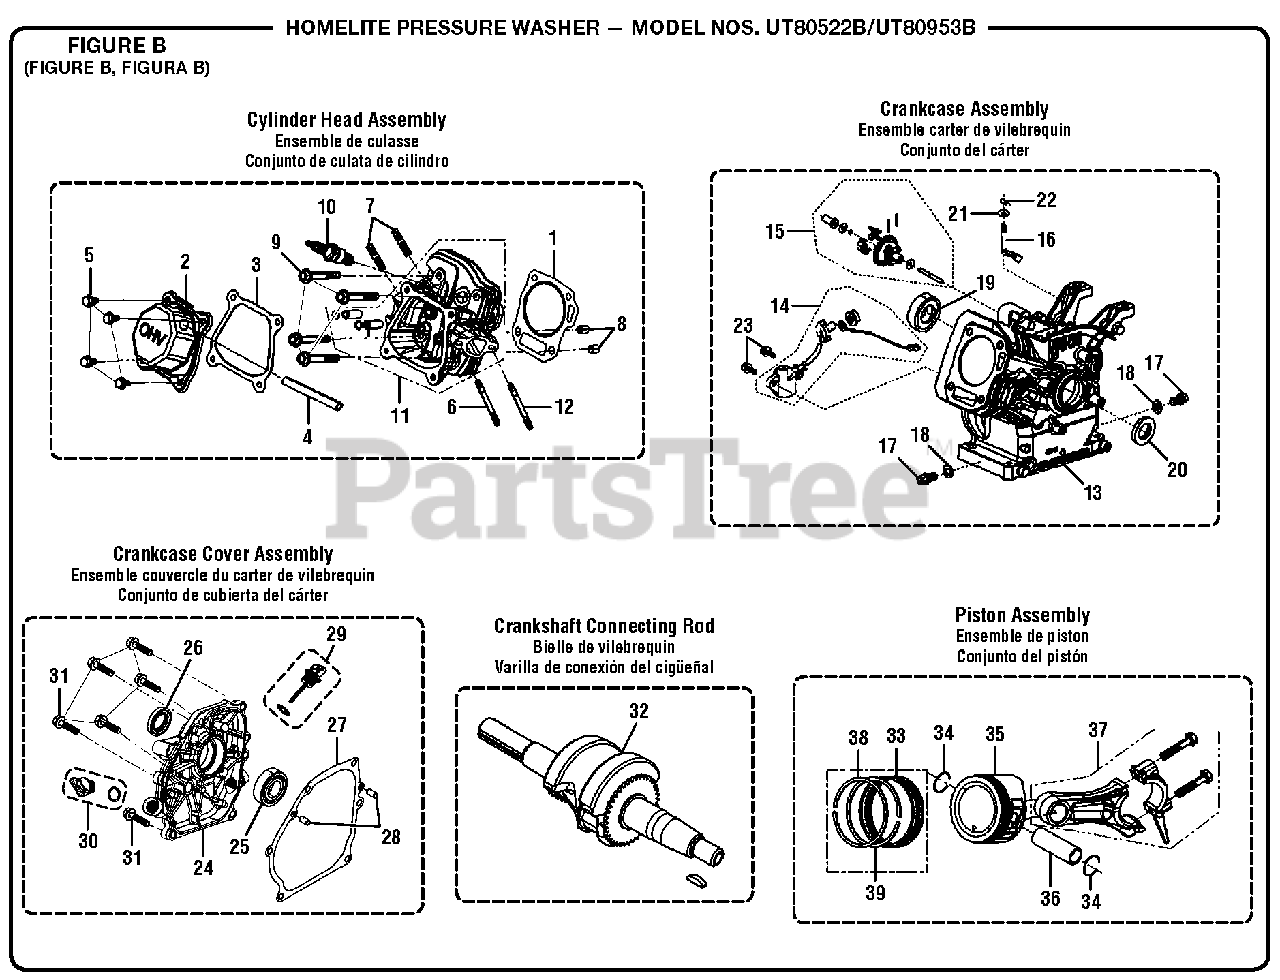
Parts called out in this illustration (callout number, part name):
1	Cylinder Head Gasket
2	Cylinder Head Cover
3	Cylinder Head Cover Gasket
9	Cylinder Head Bolt
11	Cylinder Head Assembly
13	Crankcase Assembly
14	Engine Oil Sensor
15	Governor Gear Assembly
19	Ball Bearing
24	Crankcase Cover Assembly
25	Ball Bearing
27	Crankcase Gasket
29	Oil Dipstick Assembly
30	Oil Cap Assembly
32	Crankshaft Assembly
34	Piston Pin Clip
35	Piston Assembly
39	The Second Ring
